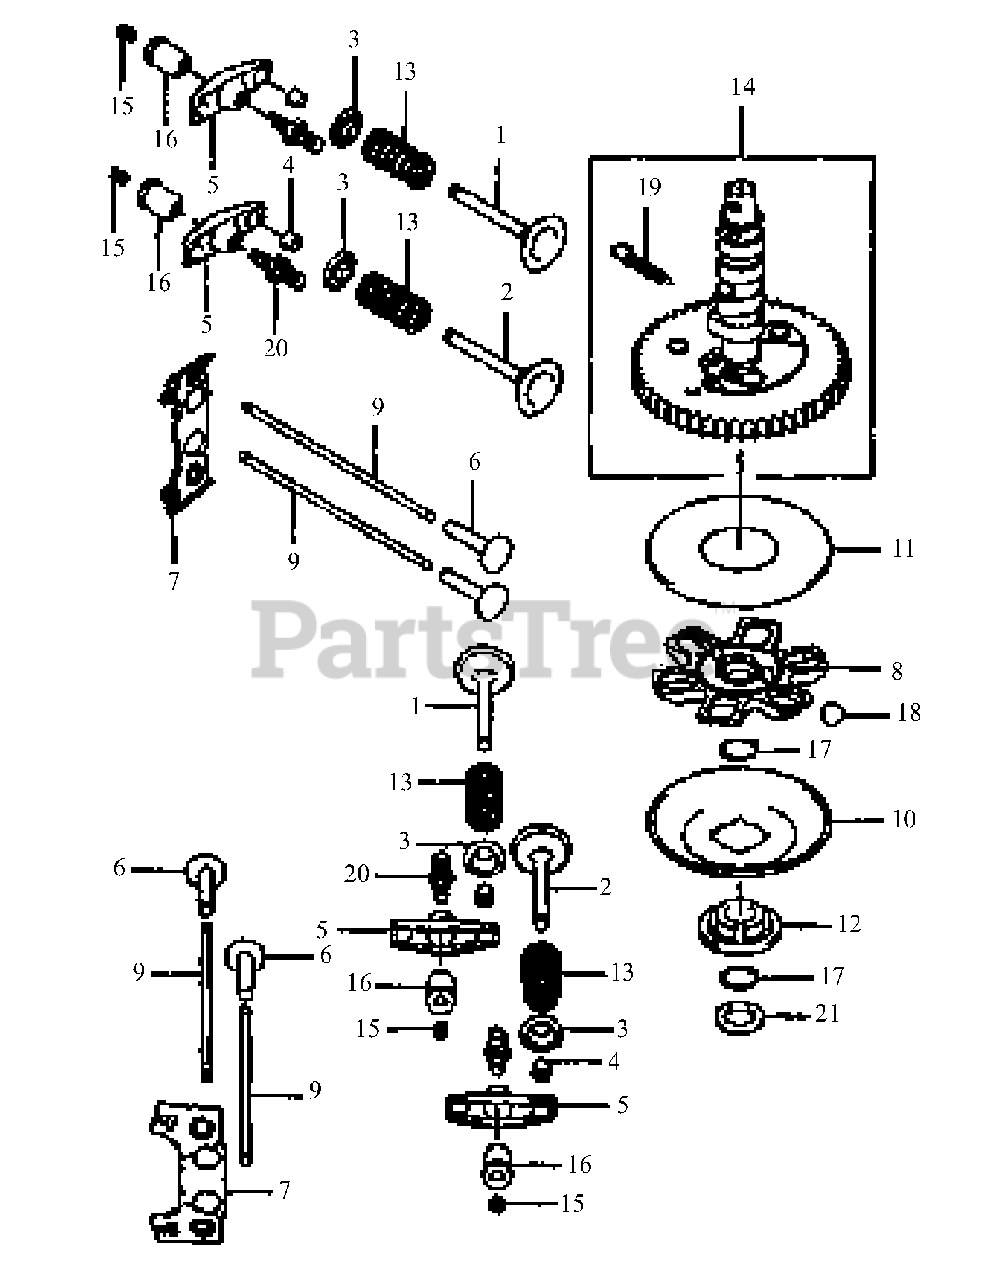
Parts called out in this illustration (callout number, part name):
1	Valve, Intake
2	Valve, Exhaust
3	Retainer, Valve Spring
13	Spring, Engine Valve
14	Camshaft, Comp.
17	Ring, Snap
18	Ball
19	Spring
